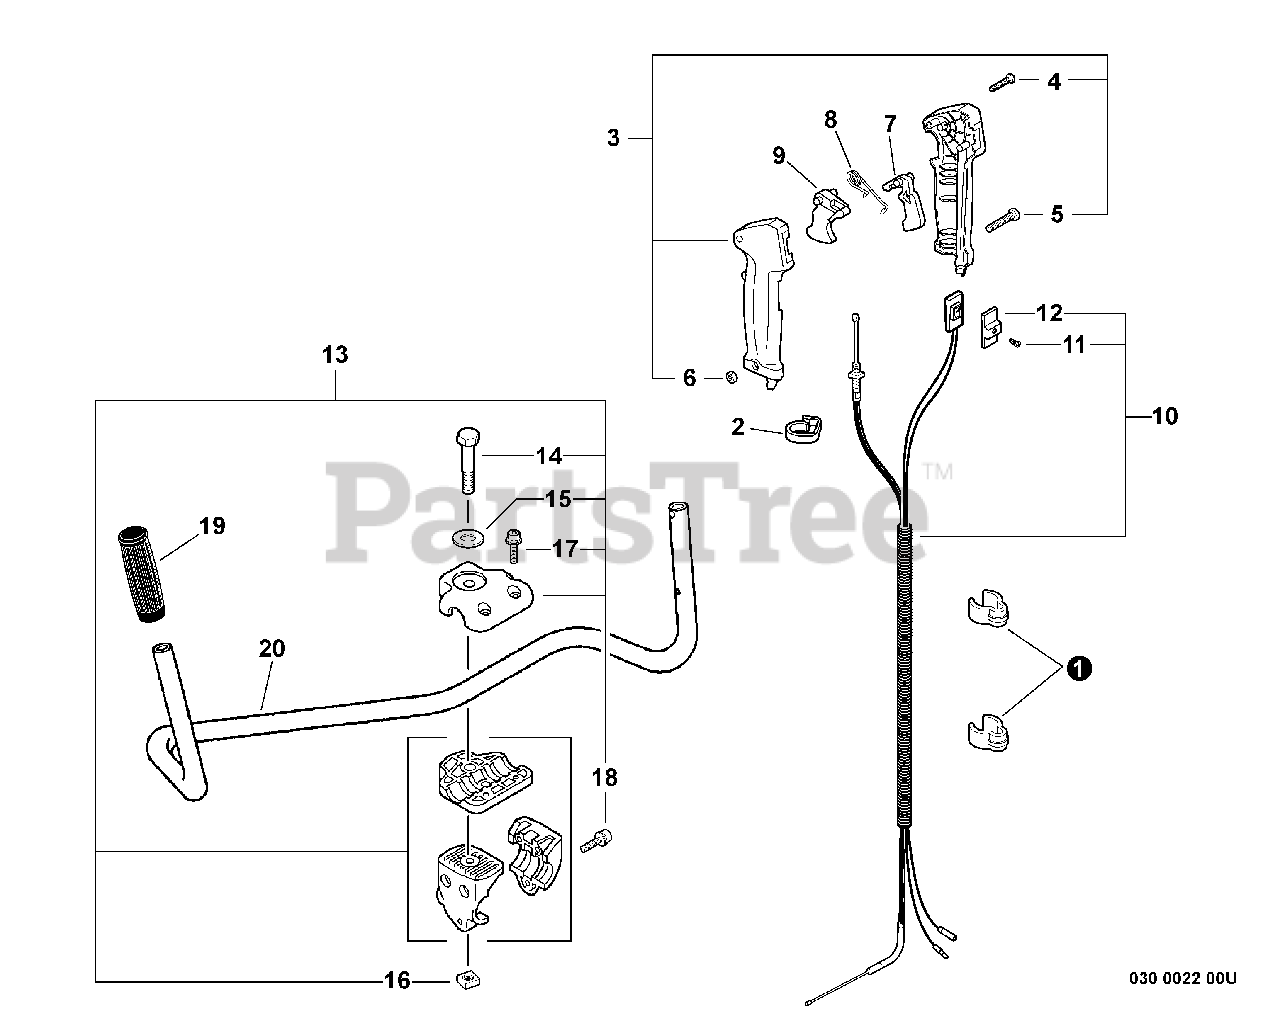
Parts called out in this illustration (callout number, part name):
3	THROTTLE CONTROL ASSY
4	SCREW - 3X25
5	SCREW - 5X30
7	LOCKOUT, THROTTLE
8	SPRING, LOCKOUT LEVER
9	TRIGGER, THROTTLE
10	CONTROL CABLE ASSY
11	SCREW - 3X10
12	KNOB, SWITCH - ORANGE
13	HANDLE BRACKET KIT
14	BOLT - 8X55
15	WASHER - 8
17	SCREW - 5X20
18	SCREW - 5X30
19	GRIP, HANDLE - LEFT
20	HANDLE - FRONT
